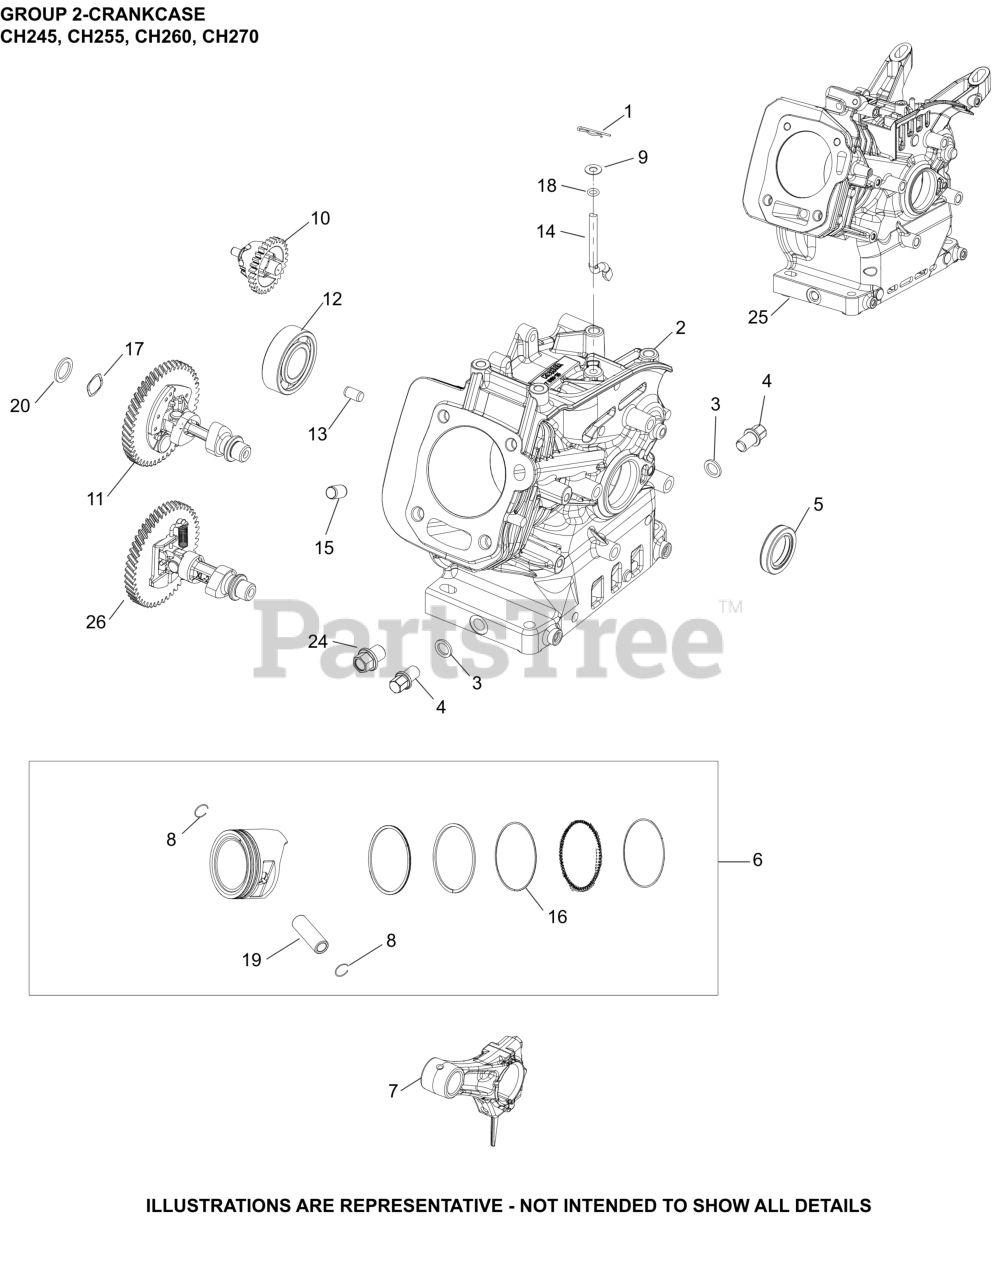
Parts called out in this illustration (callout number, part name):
1	CLIP, GOVERNOR ARM
2	CRANKCASE
3	WASHER, DRAIN PLUG - (#1846801S)
4	KIT, DRAIN PLUG
5	SEAL, OIL
6	KIT, PISTON (STD)
7	ROD, CONNECTING ASSEMBLY
8	RETAINER, PISTON PIN
9	WASHER, FLAT (13MM OD)
10	GOVERNOR ASSEMBLY
11	CAMSHAFT ASSEMBLY
12	BEARING, BALL
13	PIN, DOWEL
14	SHAFT, GOVERNOR CROSS
19	PIN, PISTON
